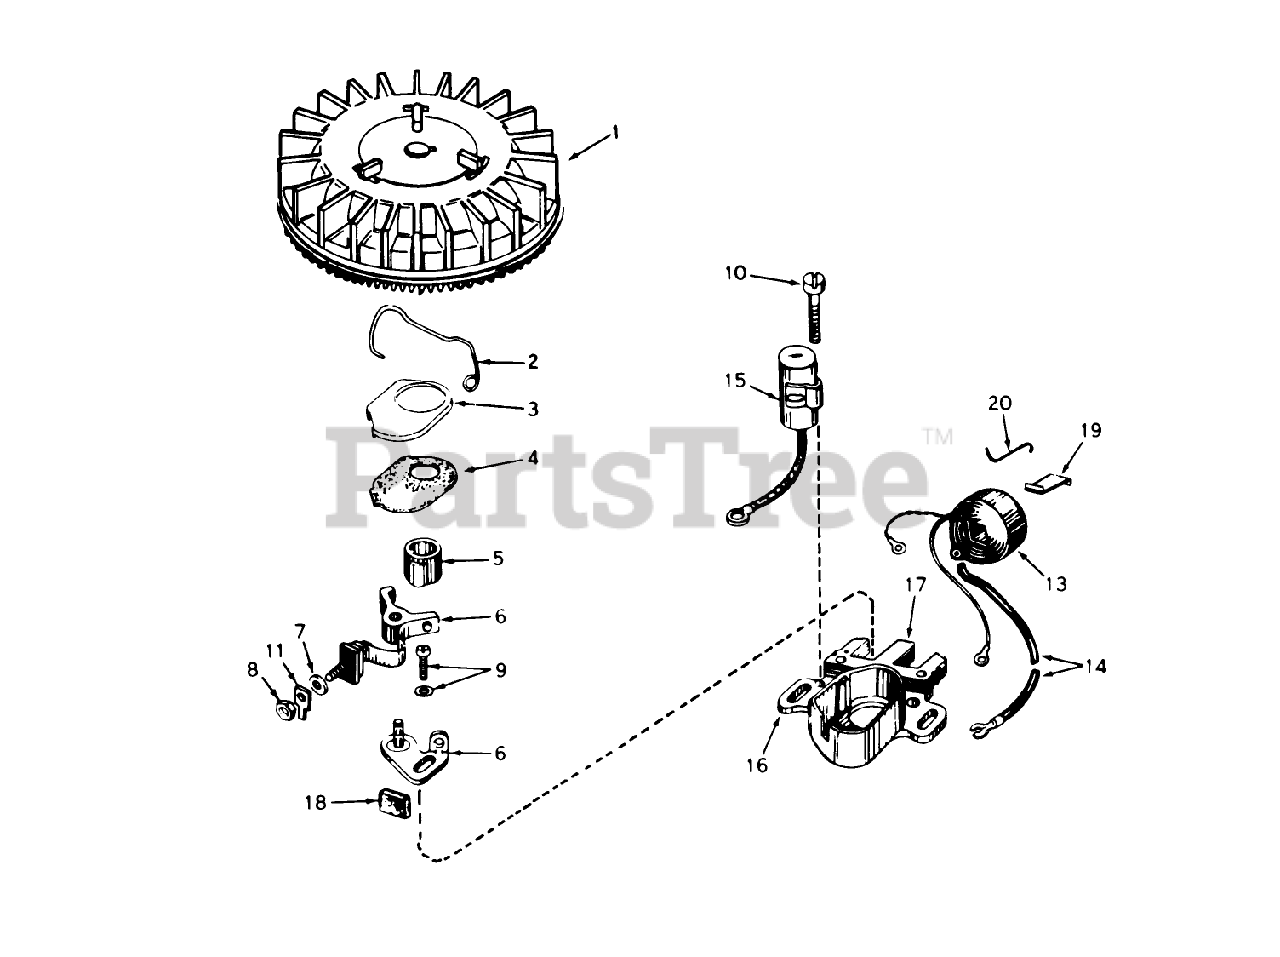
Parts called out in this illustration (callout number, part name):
1	Flywheel (Incl. Ref. #3 & 4)
2	Spring Breaker Box
3	Cover-Dust
4	Gasket, Dust Cover
5	Cam, Breaker
6	Breaker Assy.
9	Breaker Screw
10	Condenser Screw
11	Terminal, Ground
13	Coil Assembly (Incl. Ref. #14)
14	Wire, Lead
15	Condenser
16	Core & Plate
17	Stator Assembly (Incl. Ref. #2, 3, 4, 6 thru 16, 18, 19 & 20)
18	Felt,Cam Wiper
19	Spring Coil Wedge
20	Clip, Coil
